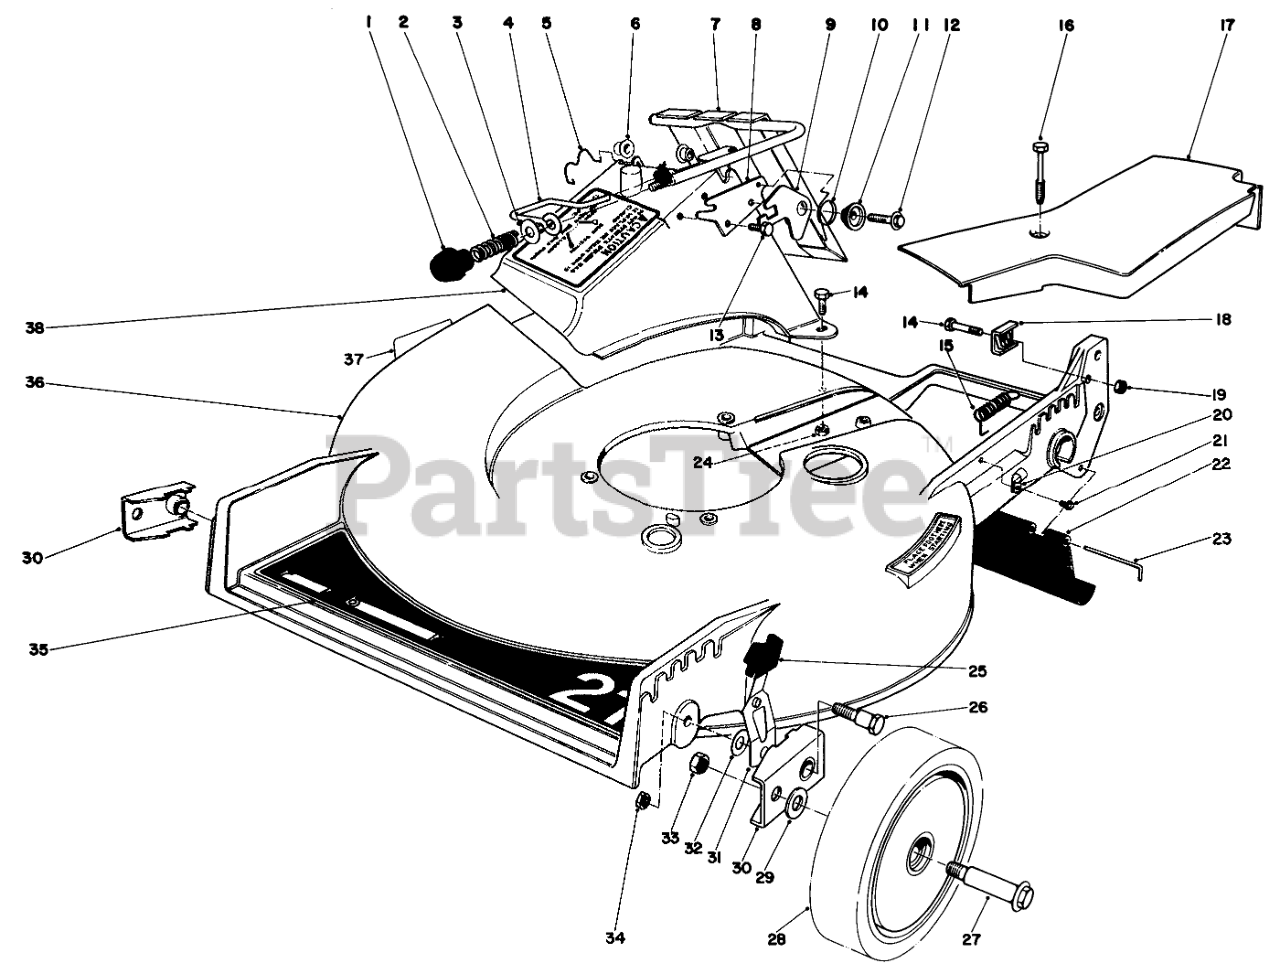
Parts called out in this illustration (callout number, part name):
2	COMPRESSION SPRING
3	WASHER-FLAT
4	DOOR LATCH
5	DOOR RETAINER
6	BUSHING-NYLON
7	DOOR & HANDLE WA
8	DOOR LATCH PLATE
9	SAFETY LATCH
10	TORSION SPRING
11	DOOR SPACER
12	Screw
13	SCREW-HWH
14	SCREW-HH
15	IDLER SPRING
16	SCREW-HHFTF
17	Belt Cover
18	CLAMP-CABLE
19	NUT-JAM
20	CLAMP-NYLON
21	SCREW-HWH
22	SHIELD-TRAILING
23	ROD-SHIELD
24	NUT-LOCK, NI
25	KNOB-ARM
26	PIVOT SCREW
27	BOLT-WHEEL
28	Wheel & Tire Assembly
29	WASHER
30	Pivot Arm
31	Spring Arm
32	WASHER-PIVOT
33	Nut
34	Nut
35	DECK DECAL
36	Housing (Incl. Ref. #37)
37	DECAL-DANGER
38	DISCHARGE CHUTE B
